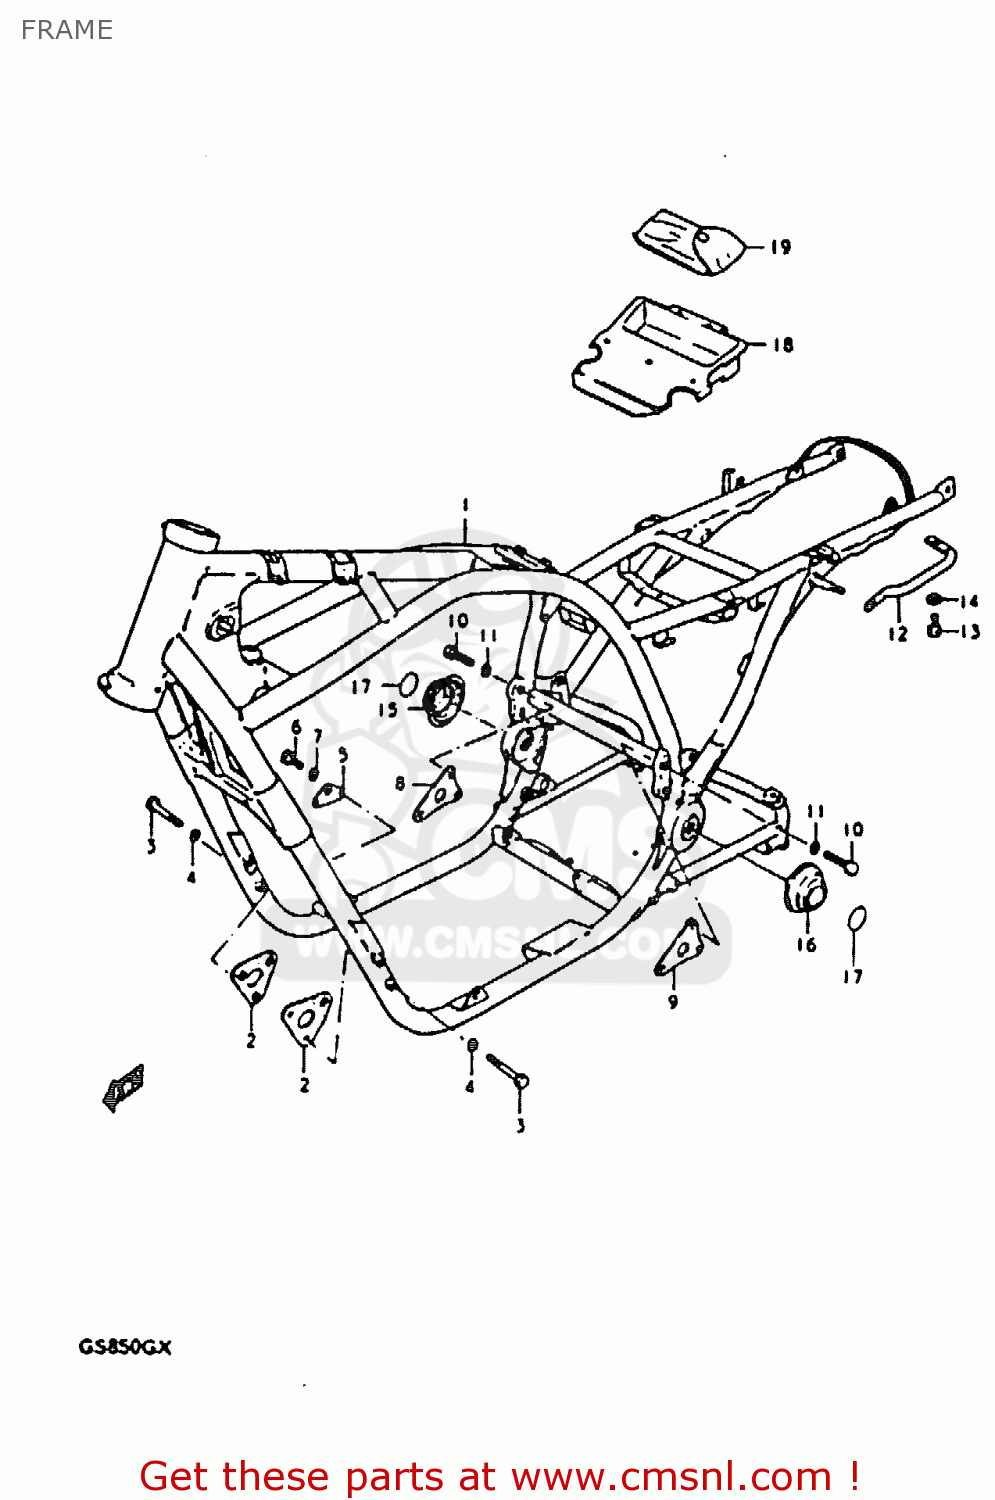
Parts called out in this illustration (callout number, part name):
1	FRAME
2	PLATE,ENGINE MOUNTING
3	BOLT
4	LOCK WASHER
5	PLATE,ENGINE MOUNTING
6	BOLT
7	LOCK WASHER
8	PLATE,ENGINE MOUNTING
9	PLATE,ENGINE MOUNTING
10	BOLT 8X40
11	LOCK WASHER
12	GRIP,FRAME
13	BOLT
14	WASHER
15	COVER,REAR SWING ARM PIVOT
16	COVER,SWINGINGARM PIVOT,L
17	TAPE,REAR SWING ARM PIVOT
18	HOLDER,TOOL
19	TOOL SET
